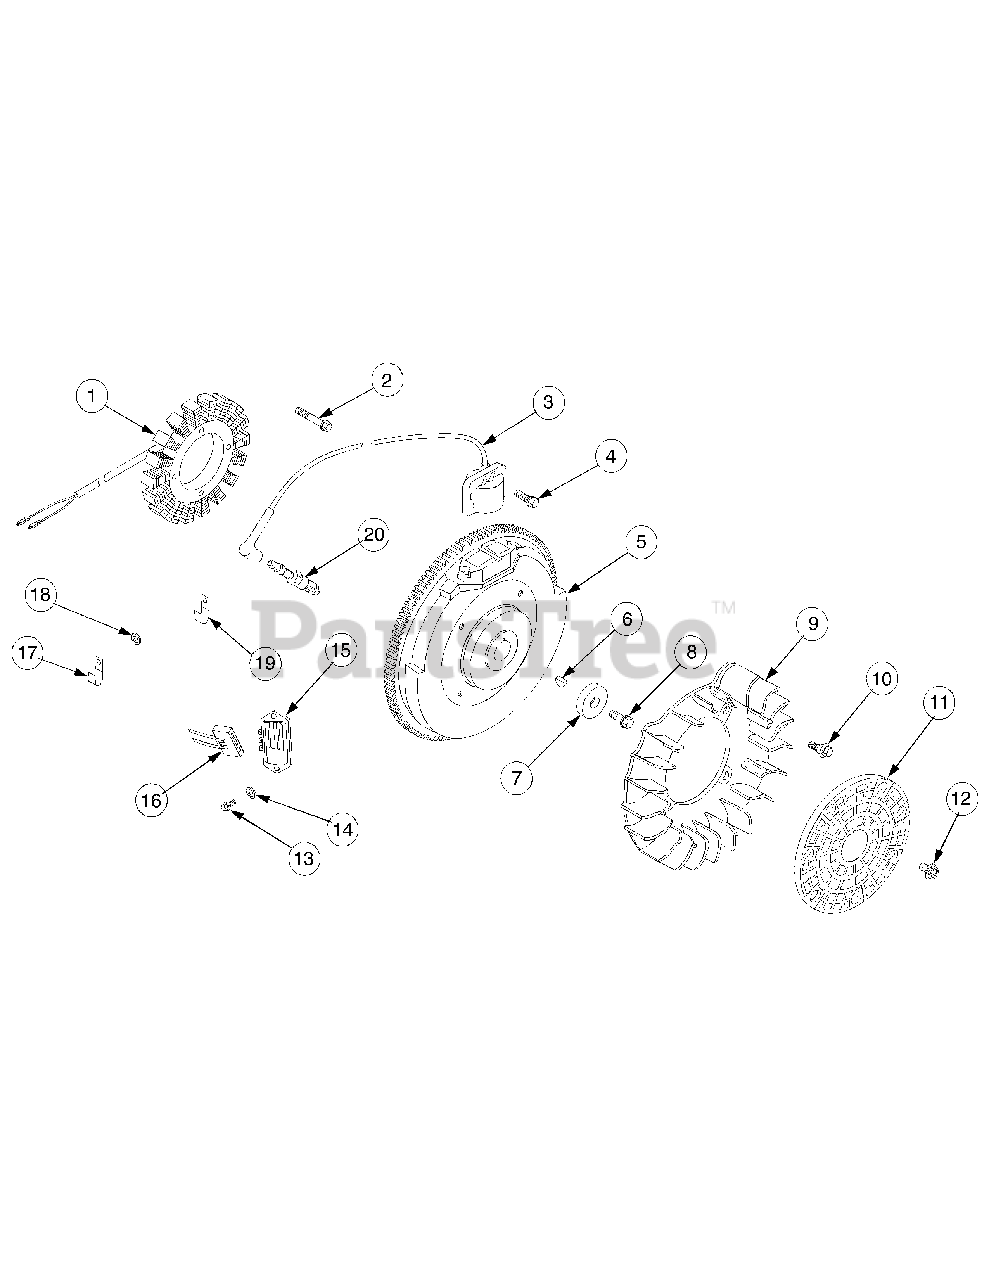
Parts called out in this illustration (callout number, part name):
1	Stator Kit, 15 Amp
2	Screw, Stator Mtg. M5 x .8 x 25
3	Module, Ignition
4	Screw, Module M5 x .8 x 20
5	Flywheel Assembly
7	Washer, Flat, 13/32
8	Screw, Flange M10x1.5 x 45
9	Fan
10	Bolt, Shoulder
11	Screen, Grass
13	Screw Phillips Hd., #11-16 x .875
14	Washer, Plain
15	Regulator - Rectifier
16	Connector, Regulator-Rectifier
17	Clip, Cable
18	Washer, Plain 1/4"
20	Spark Plug
